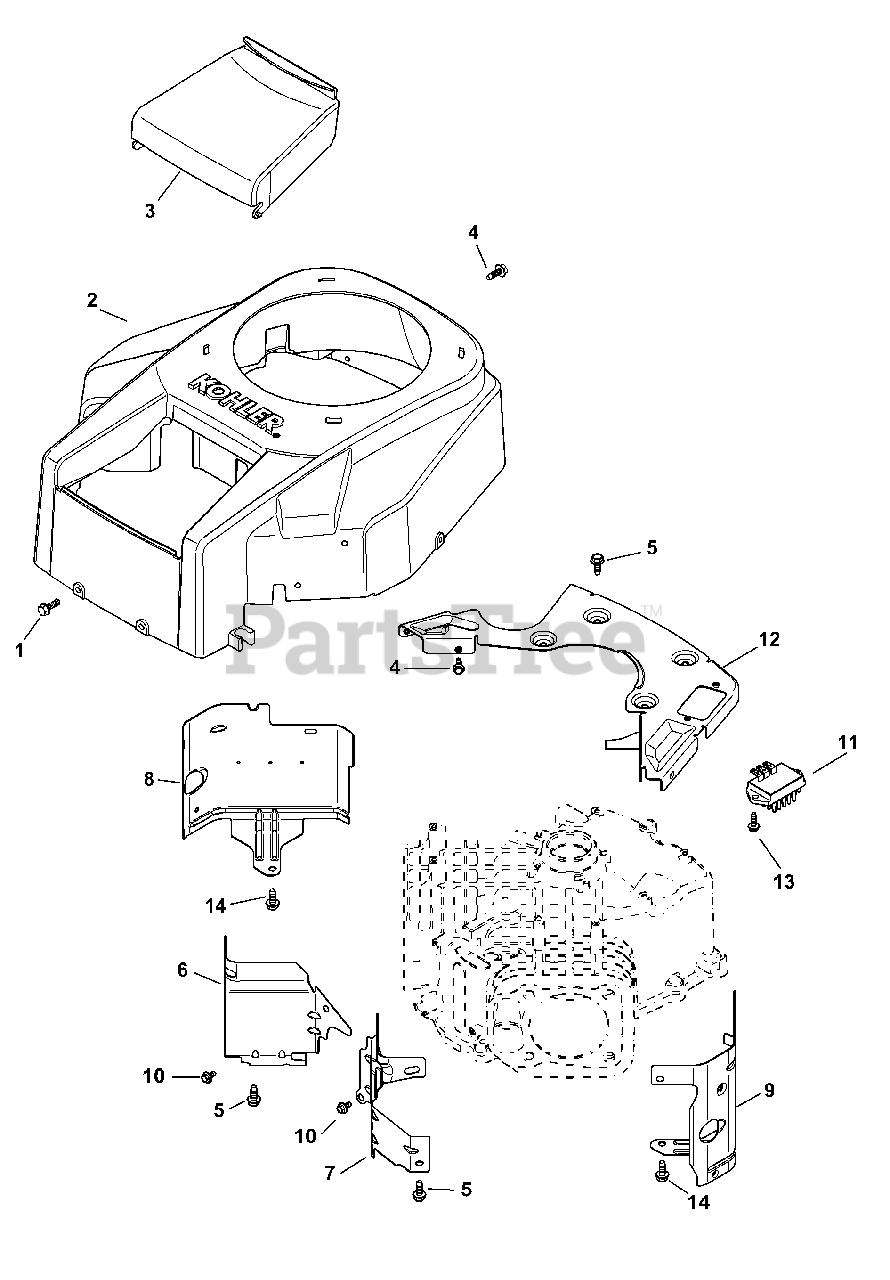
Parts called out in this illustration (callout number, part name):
1	Screw, M6 x 1.7 x 18
2	Blower Housing Kit
3	Air Cleaner Cover
4	Flange Screw, M5 x .8 x 16
5	Flange Screw, M6 x 1.0 x 16
6	Valley Baffle, #1 Cylinder
7	Valley Baffle, #2 Cylinder
8	Cylinder Barrel Baffle, #1 Side
9	Cylinder Barrel Baffle, #2 Side
10	Flange Screw, M5 x .8 x 10
11	Regulator/Rectifier
12	Backing Plate Kit
13	Screw, M5 x .8 x 20
14	Flange Screw, M6 x 1.0 x 10
